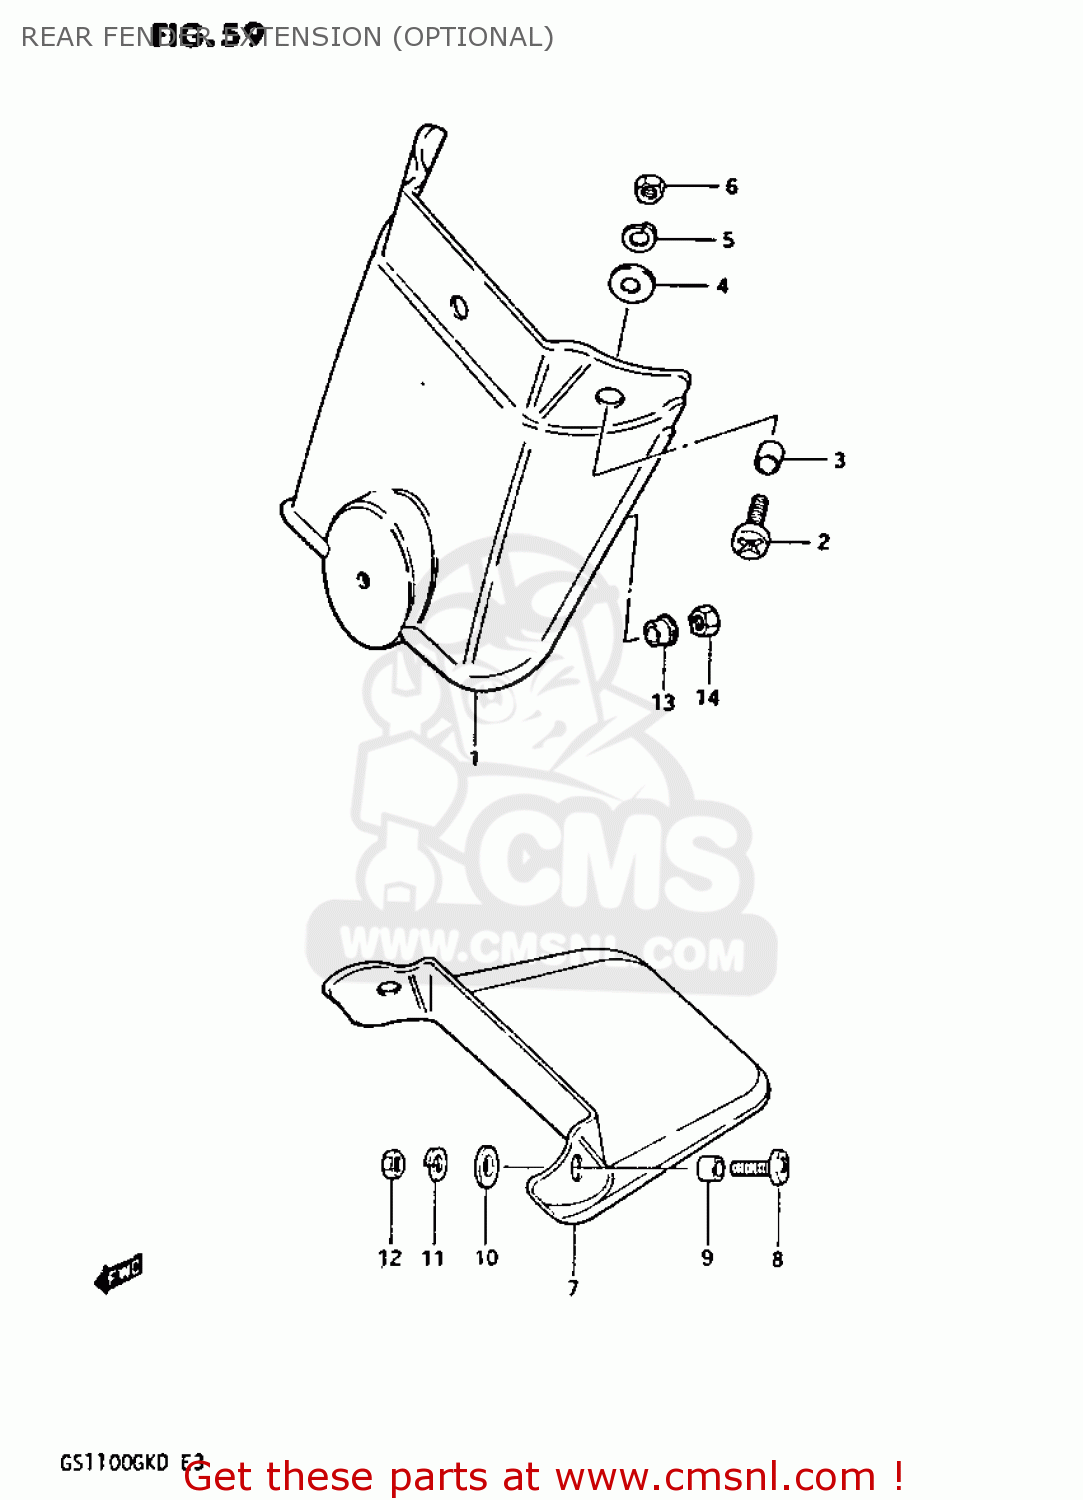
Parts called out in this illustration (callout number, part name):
1	EXTENSION,REAR FENDER
2	SCREW (6X15)
3	SPACER(6.2X8.3X5.7)
4	WASHER(6.5X18X1)
5	WASHER,LOCK
6	NUT
7	EXTENSION,REAR FENDER
8	SCREW (6X15)
9	SPACER(6.2X8.3X5.7)
10	WASHER(6.5X18X1)
11	WASHER,LOCK
12	NUT
13	WASHER
14	NUT
